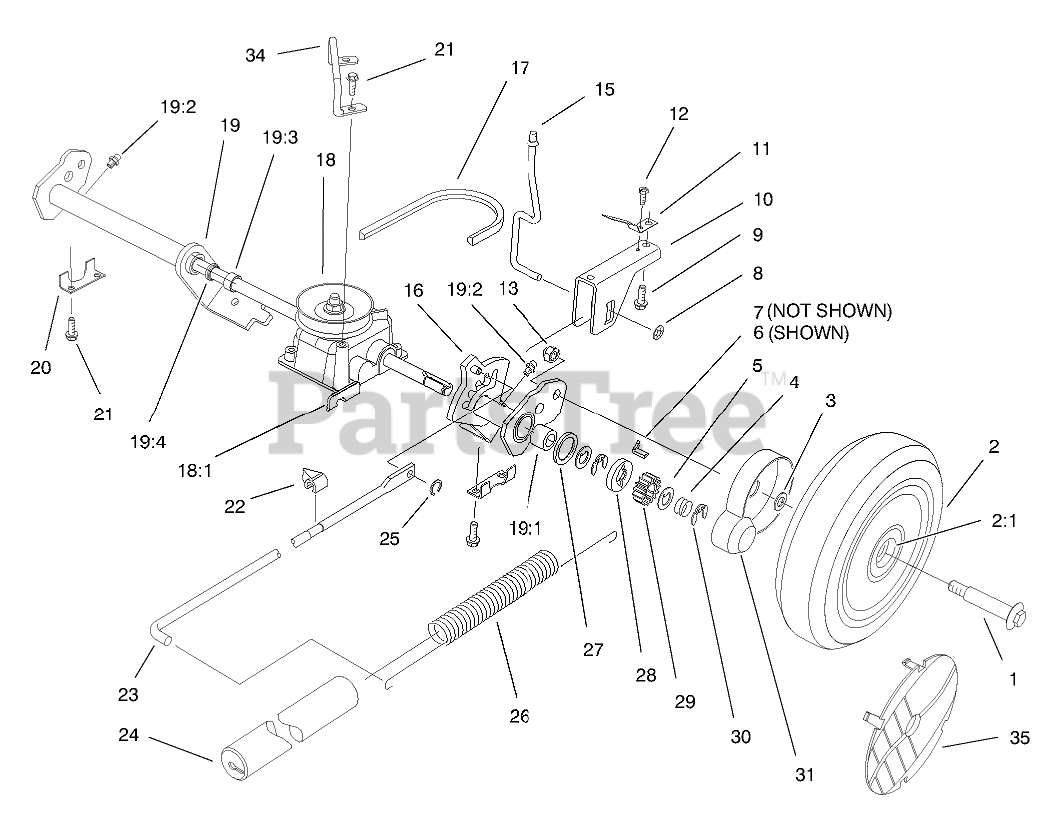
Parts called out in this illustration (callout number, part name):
1	BOLT-WHEEL
2	WHL & TIRE ASSEMBLY
2:1	BUSHING
3	SPACER-COVER, WHEEL
4	SPRING-COMPRESSION
5	WASHER-THRUST, KEYED
6	KEY-ROCKING, LH
7	KEY-ROCKING, RH
8	PUSHNUT
9	SCREW
10	SADDLE - HOC
11	SPRING - TRIGGER RET
12	SCREW 8 - 32 X 250
13	NUT-HEX
15	TRIGGER ROD
16	ASM - LH PIVOT ARM
17	V-BELT
18	GEAR CASE ASSY
18:1	TRACTION BRACKET
19	ASM - RH PIVOT ARM
19:1	BEARING-ROLLER
19:2	FITTING-GREASE
19:3	BUSHING
19:4	SEAL-OIL
20	REAR SECURING PLATE
21	SCREW-HWH
22	INDICATOR-HEIGHT OF CUT
23	LINK ROD
24	COVER-SPRING
25	GRIP RING
26	SPRING-COUNTERBALANCE
27	RING-FRICTION
28	WASHER-CLUTCH
29	GEAR-PINION
30	RING-CLIP, LOCKING
31	COVER-WHEEL
34	Retainer Belt
35	COVER-WHEEL
